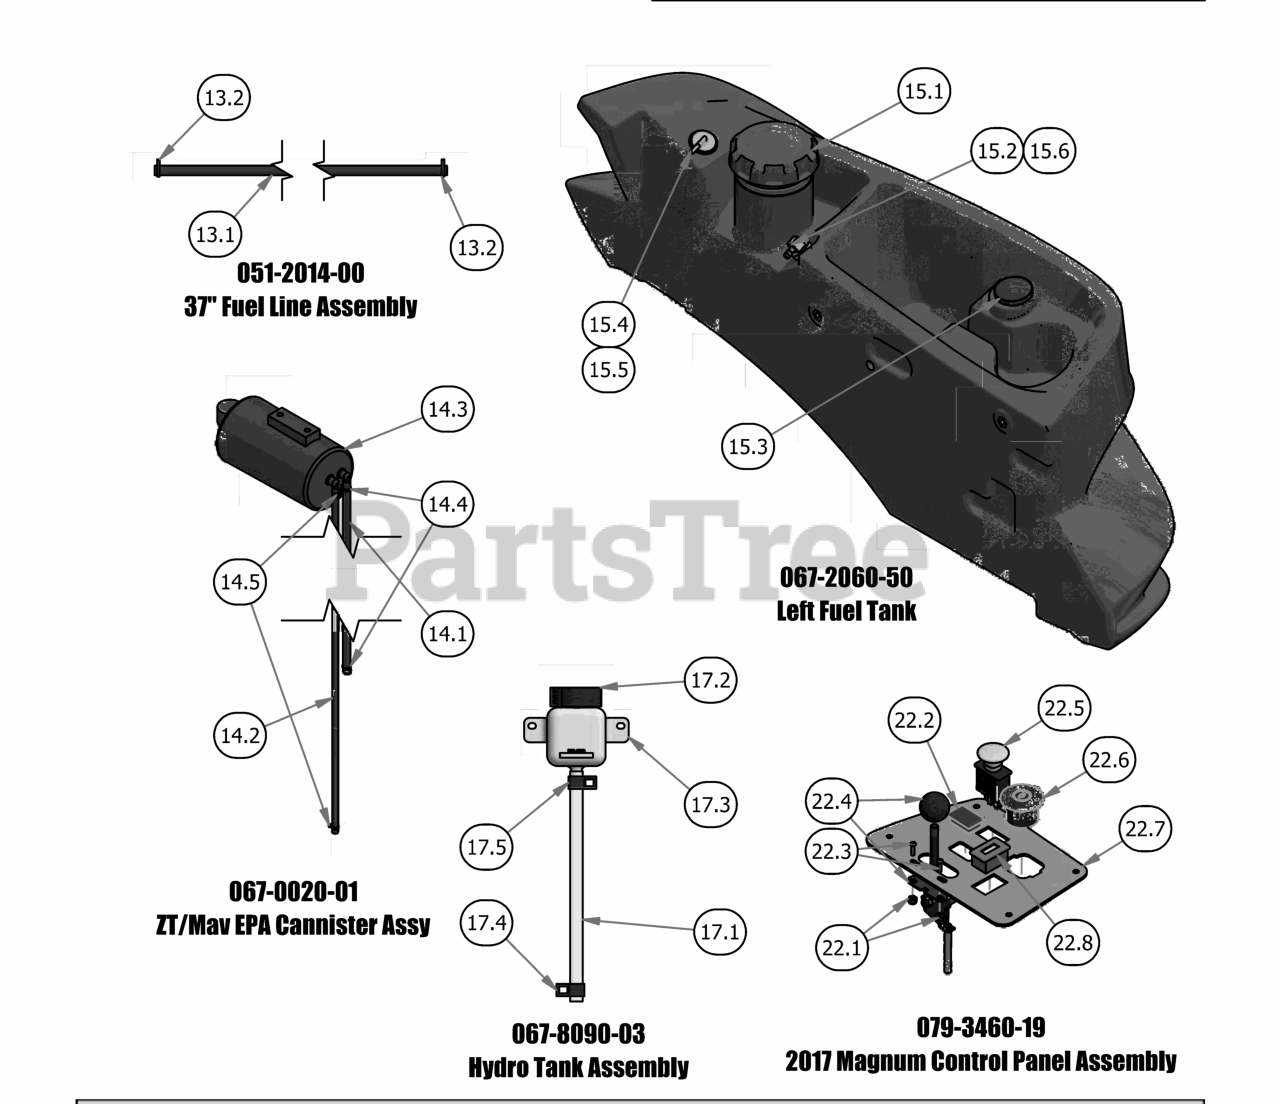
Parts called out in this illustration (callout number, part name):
13.1	37" 1/4 Fuel Line
13.2	1/4 Fuel Hose Clamp
14.1	1/4" Vinyl Tubing, 46" Long
14.2	3/16" Vinyl Tubing, 55" Long
14.3	Carbon Canister
14.4	3/16 Vinyl Clamp
14.5	3/16" Vinyl Hose Clamp
15.3	Fuel Gauge w/Grommet
15.4	Rollover Valve
15.5	Rollover Valve Grommet
15.6	Pick-Up Grommet
17.1	ZT/Maverick Hydro Tank Hose
17.2	Hydraulic Tank Cap
17.3	350ml Expansion Tank
17.4	3/8" Hose Clamp
17.5	1/2 Hose Clamp
22.1	10-24 Nylon Insert Locknut Zinc Orange Nylon
22.2	Light Plug
22.3	10-24 X 5/8 BS Button Head Bolt
22.4	Throttle Lever Assembly
22.5	PTO Engager
22.6	Ignition Switch
22.7	Control Panel
22.8	Tachometer
